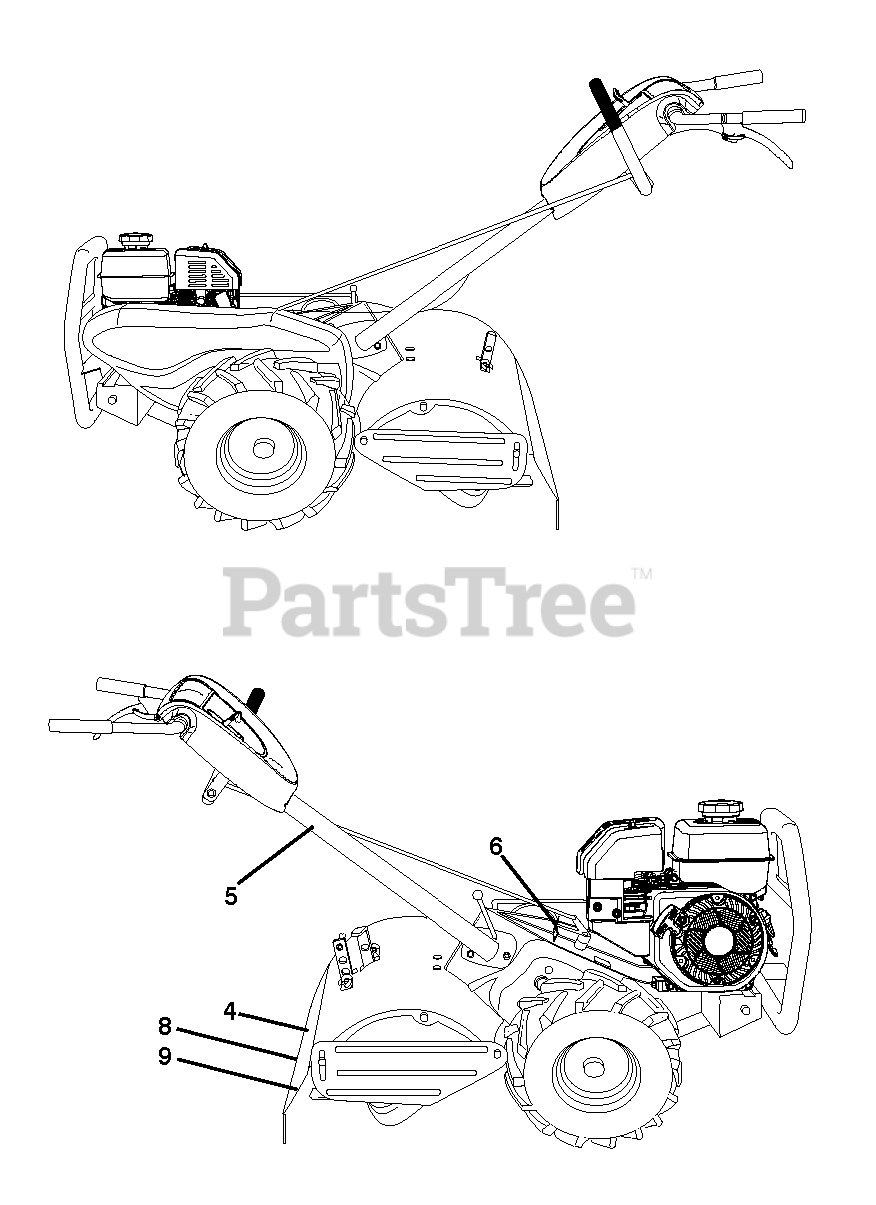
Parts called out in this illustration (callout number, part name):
4	DECAL TILLER TINE SHIELD GRAPH
5	DECAL.PLACEMENT.HAND.SYMBOLS
6	DECAL.INDICATOR.SHIFT.DRT.SYM
8	DECAL TILLER TINE SHIELD GRAPH
9	DECAL.WARNING.4-SYM.TILLER.INT
